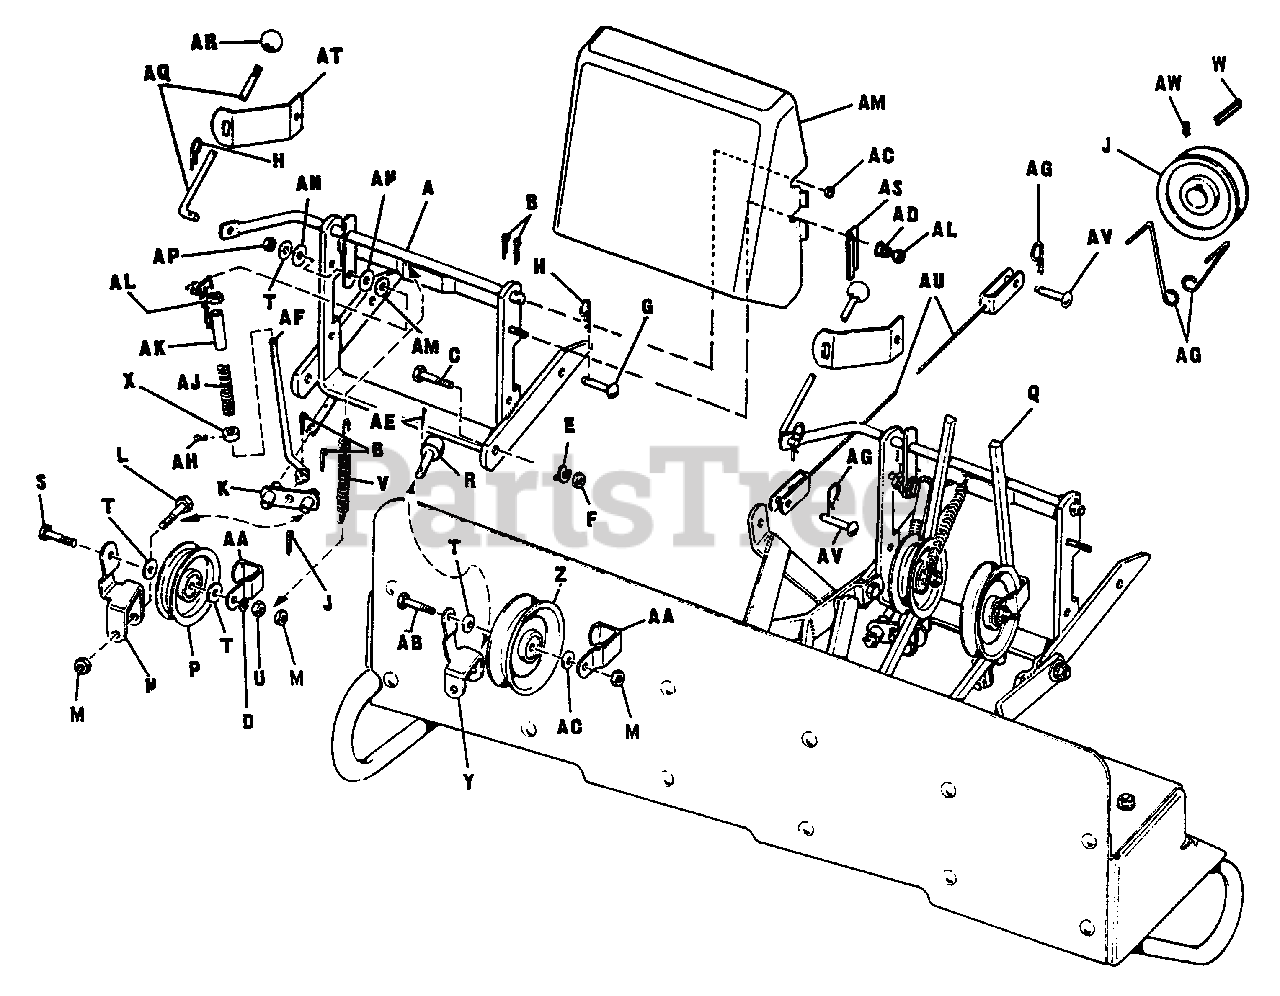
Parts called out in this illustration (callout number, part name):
A	Hitch Assembly
B	Cotter Pin, 1/8" Dia. x 1" lg.
C	Hex. Cap Screw
D	Lock Washer
E	Spring Washer, 3/8"
F	Full Lock Hex. Nut, 3/8"-24
G	Pin
H	Spring Clip
K	Idler Lever Assembly
L	Hex. Cap Screw, 3/8"-16 x 2-1/4"
M	Full Lock Hex. Nut, 3/8"-16
N	Idler Bracket
P	Idler Pulley
S	Hex. Cap Screw, 3/8"-16 x 1-1/2"
T	Plain Washer, 5/16"
U	Jam Hex. Nut, 3/8"-16
V	Return Spring
Y	Idler Bracket
Z	Idler Pulley
AA	Belt Guide
AB	Hex. Cap Screw, 3/8"-16 x 1-1/4"
AD	Conical Spring
AE	Cotter Pin, 3/32" Dia. x 3/4"
AF	Clutch Rod
AH	Set Screw, 1/4"-20 x 3/8"
AK	Rod Guide Assembly
AL	Full Lock Hex. Nut, 5/16"-18
AM	Pulley Cover
AN	Nylon Washer
AP	Stop Nut, 5/16"-18
AQ	Clutch Handle
AS	Clip, Pulley Cover
AU	Cable Assembly
AW	Set Screw, 3/8"-24 x 3/8"
